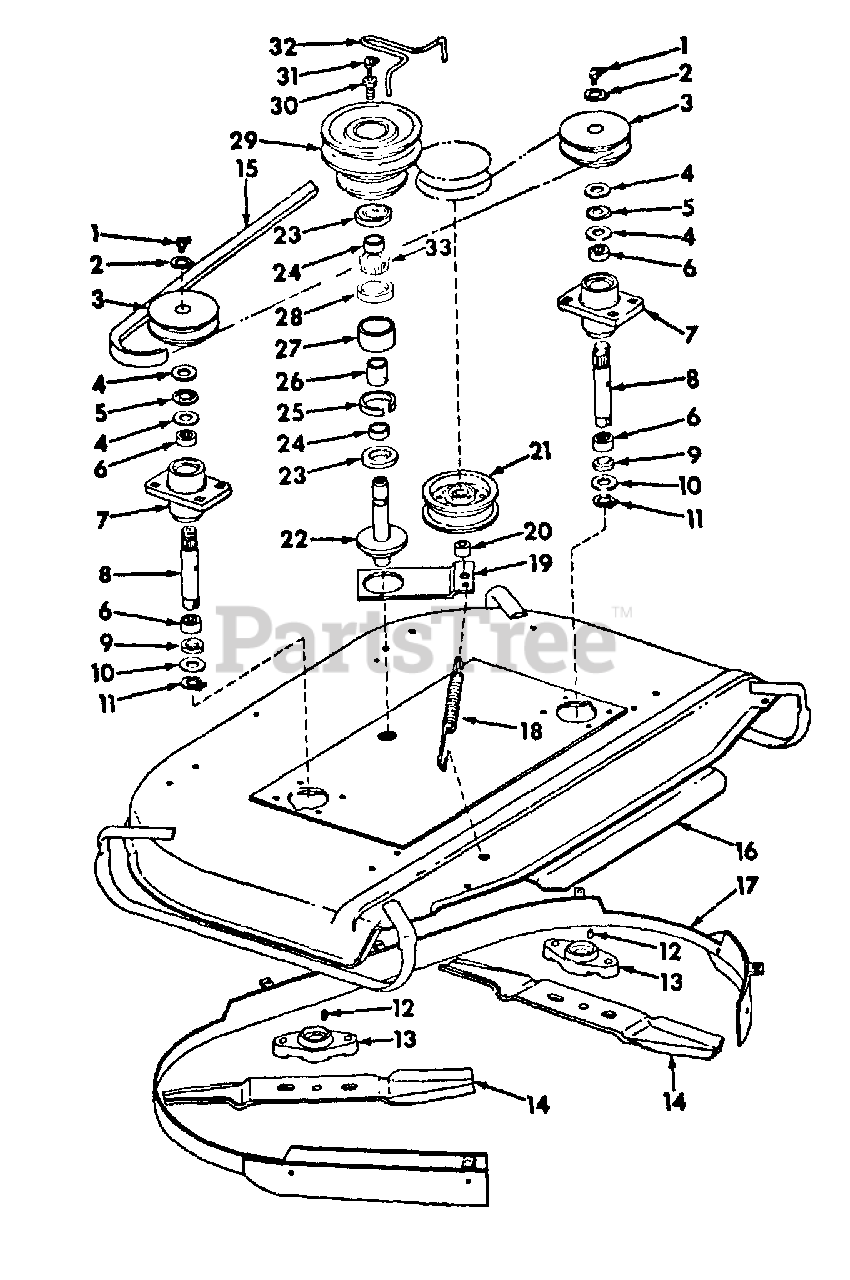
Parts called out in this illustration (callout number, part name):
1	FITTING, 3/16 ANGLE DRIVE LUB
3	PULLEY, BLADE
4	WASHER, THRUST
5	BEARING, NEEDLE
6	BEARING, NEEDLE
7	HOUSING, BLADE SHAFT
8	SHAFT, NEEDLE
9	SEAL, GREASE
10	WASHER, THRUST
11	RING, SNAP
12	KEY, 3/16 X 1/2 SQ PARALLEL
13	ADAPTER, BLADE
14	BLADE, 32 IN MOWER -HARD SURFACED-
15	BELT, BLADE DRIVE
16	HOUSING ASSY, MOWER
17	SHROUD ASSY, MOWER
18	SPRING, PEDAL RETURN
20	SPACER, IDLER PULLEY
21	IDLER, BALL BRG
23	SEAL, SPINDLE OIL
24	SPACER, PULLEY
25	SPACER, SPLIT OUTER
26	SPACER, SPINDLE BEARING
27	BUSHING, BRG OD
28	BEARING ASSY, SPINDLE
29	PULLEY, CENTER SPINDLE
30	BOLT, END
31	FITTING, 3/16 45 DEG DRIVE TYPE LUB
32	GUIDE, PTO BELT
33	CONE, SPINDLE BEARING
